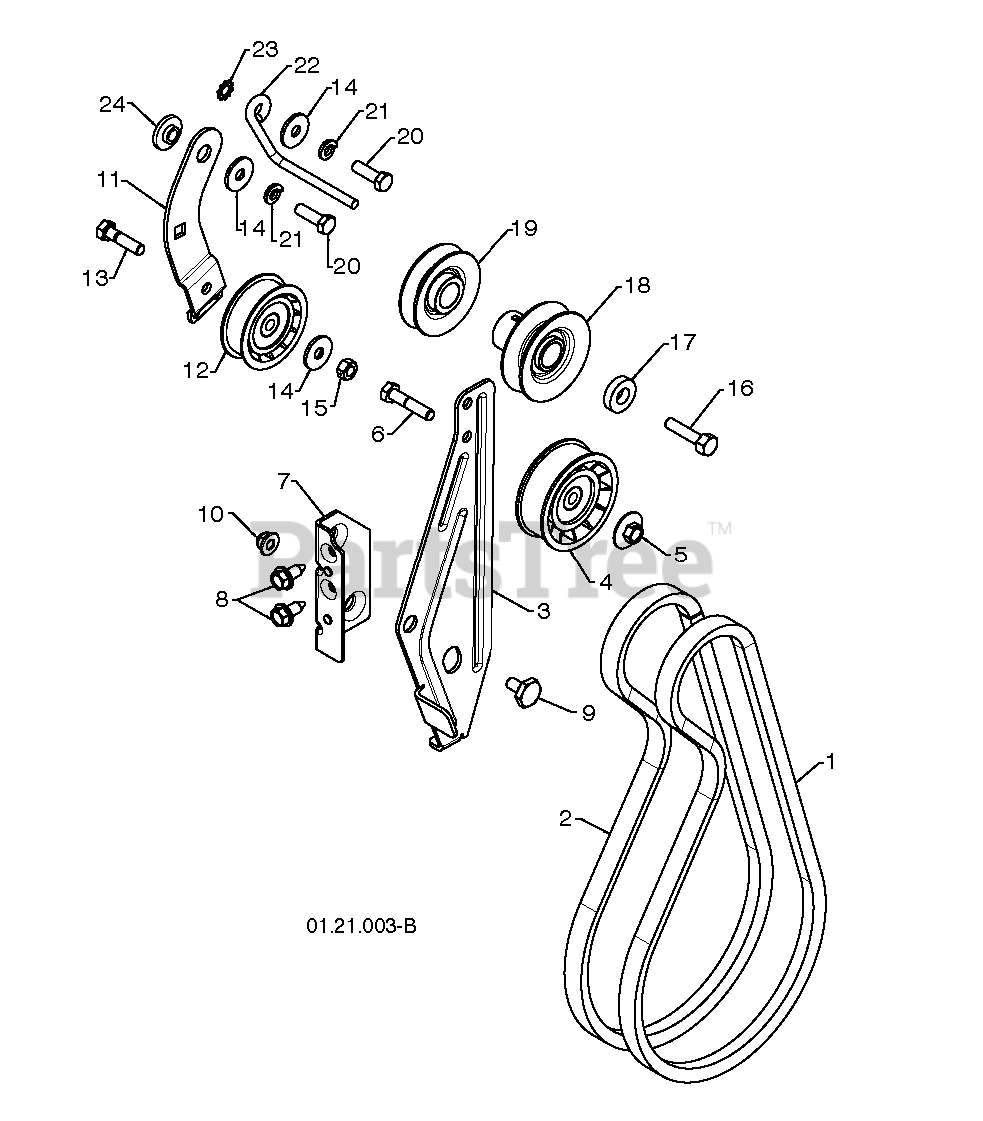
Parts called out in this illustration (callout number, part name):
1	VBELT; IMPELLER_39.09
2	V-BELT TRACTION 34.25
3	ARM.IDLER.BRAKE
4	PULLEY.IDLER.W/SPACER.
5	NUT.FLANGE.HEX.5/16X18.BLACK
6	HEX BOLT
7	RP BRACKET.IDLER
8	BOLT.HEX.HD.WASHER.5/16-18X.75
9	BOLT.SHOULDER.1/2X12
10	NUT.LOCK.5/16-18
11	ARM, IDLER
12	PULLEY.W/SPACER.2.25
13	BOLT.5/16-18X1-1/4 FULL.THREAD
14	STEEL WASHER
15	NUT.71038.31-18.HEX.NYLOCK
16	SCREW, HEX HD 3/8-24 X 1-3/8
17	WASHER, FLAT 3/8
18	PULLEY.IMPELER.
19	PULLEY.ENG.TRACTION
21	WASHER.LOCK.HVY.HLCL.SPR.5/16
22	BELT.GUIDE.RH
23	WASHER EXT TOOTH LOCK 5/16
24	RP BUSHING, IDLER PIVOT
